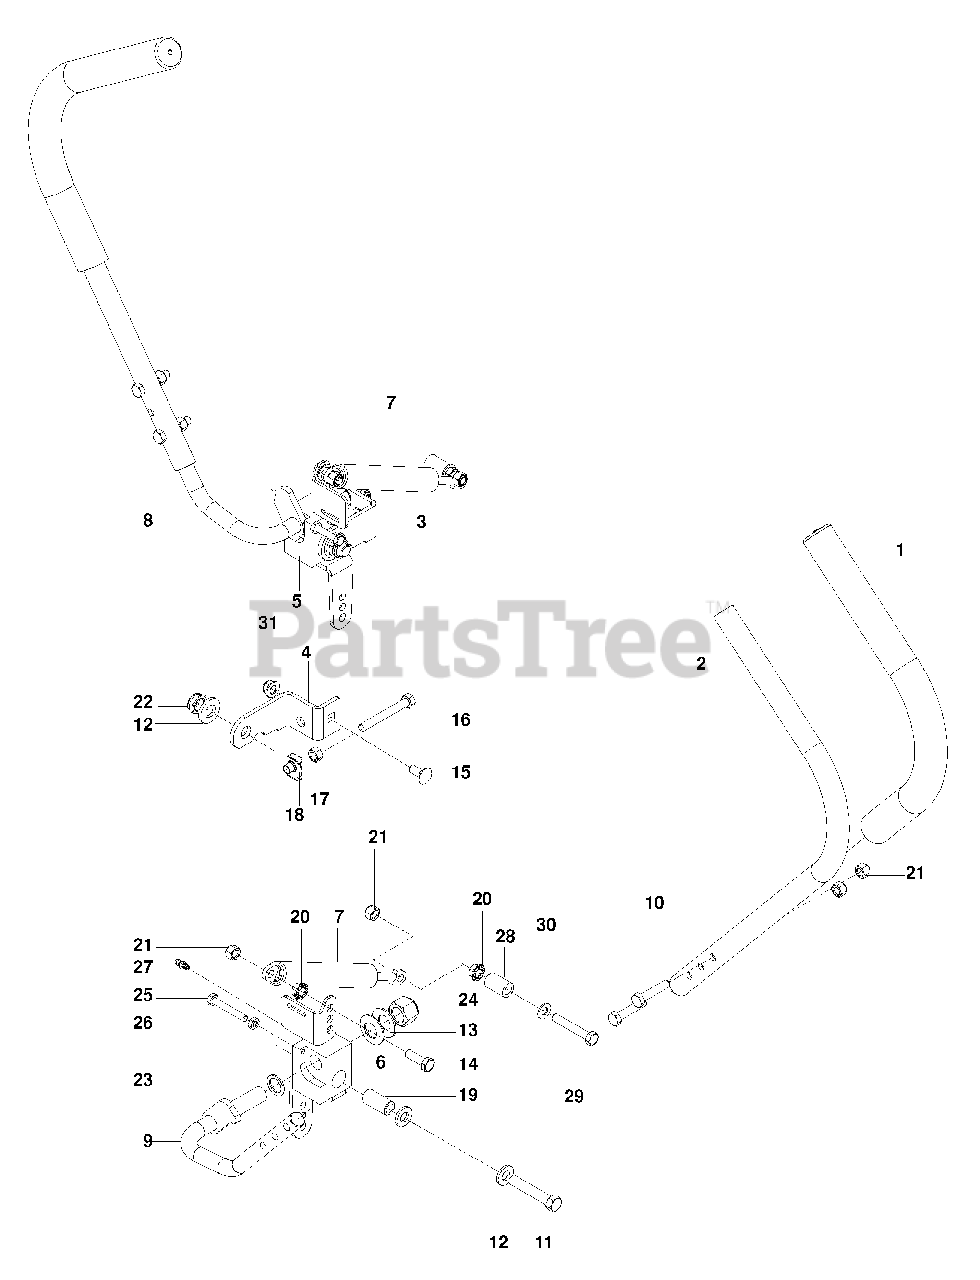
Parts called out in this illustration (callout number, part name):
2	LEVER, UPPER
3	STOP, STEER CNTRL RH
4	STOP, STEER CNTRL LH
8	LOWER LEVER, RH
9	LOWER LEVER, LH
10	HCS 5/16-18 x 1 1/2
11	HCS 1/2-13 x 2 3/4
12	WASHER 1/2 SAE
13	WASHER 5/8 BELLEVILLE
14	HCS 5/16-18 x 1
15	RHSNB 5/16-18 x 3/4
16	HCS 5/16-18 x 2 1/2
17	NUT, 5/16-18 HEX
18	RETAINER, U TYPE
19	BUSHING 1/2 ID x 3/4 OD
20	NUT 5/16-18 HEX WHIZLK
21	NUT 5/16-18 HEX NYLOC
22	NUT 1/2-13 JAM NYLOC GR 2
23	WASHER, SPECIAL
24	NUT 5/8-11 NYLOC
25	HCS 1/4-20 x 13/4
26	NUT 1/4-20 JAM
27	ZERK
29	HCS 5/16-18 x 2
30	WASHER 5/16 SAE FLT
31	NUT 5/16-18 FLG HEX NYLOC
